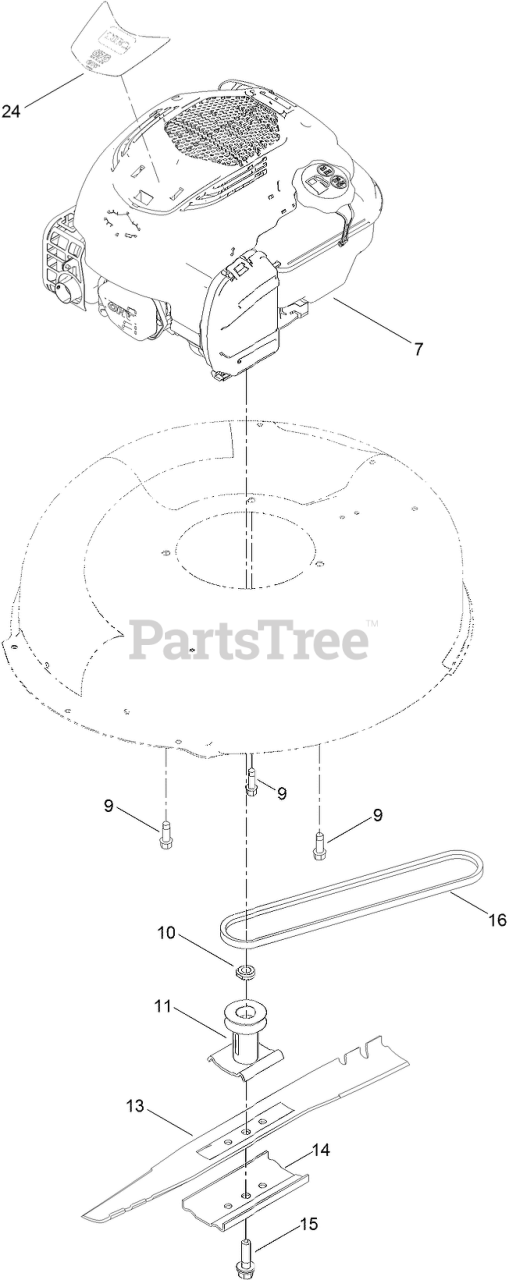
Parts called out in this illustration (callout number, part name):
9	SCREW-TAPTITE
10	SPACER-DRIVER
11	DRIVER-BLADE
13	BLADE-21IN
14	SUPPORT-BLADE
15	BOLT-BLADE
16	V-BELT
24	DECAL-SHROUD
